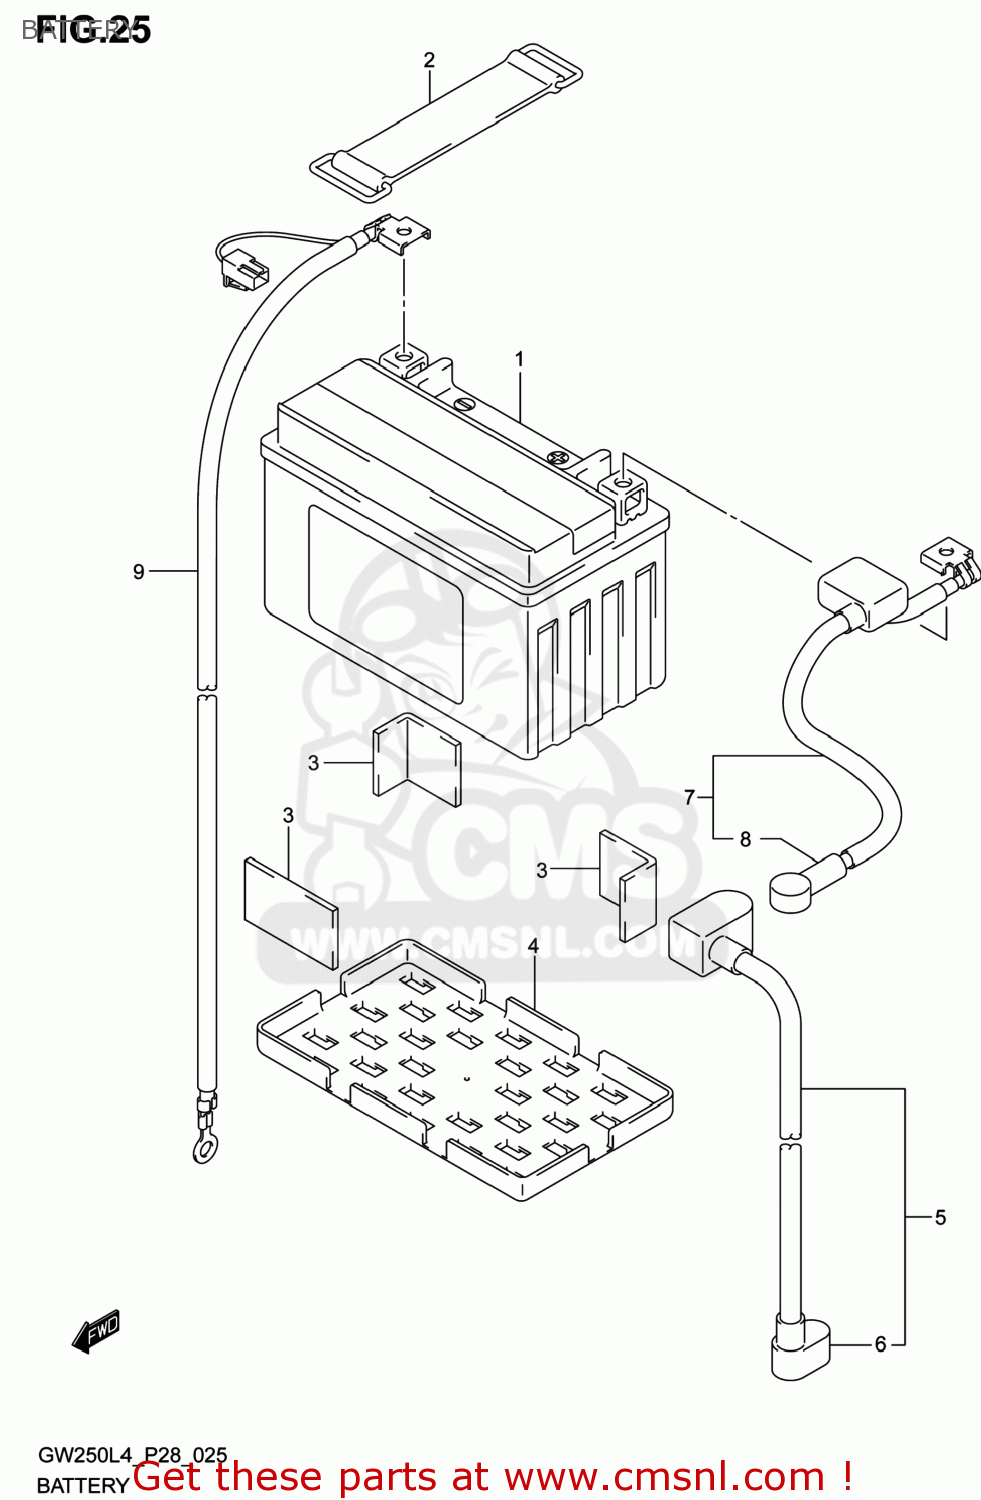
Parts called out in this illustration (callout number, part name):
1	BATTERY ASSY(YTX9-BS,12V8AH)
2	BAND,BATTERY
3	PROTECTOR,BATTERY
4	PROTECTOR,BATTERY
5	WIRE,STARTER MOTOR LEAD
6	CAP,STARTER MOTOR RELAY
7	WIRE,BATTERY PLUS LEAD
8	CAP,STARTER MOTOR RELAY
9	WIRE,BATTERY MINUS LEAD
